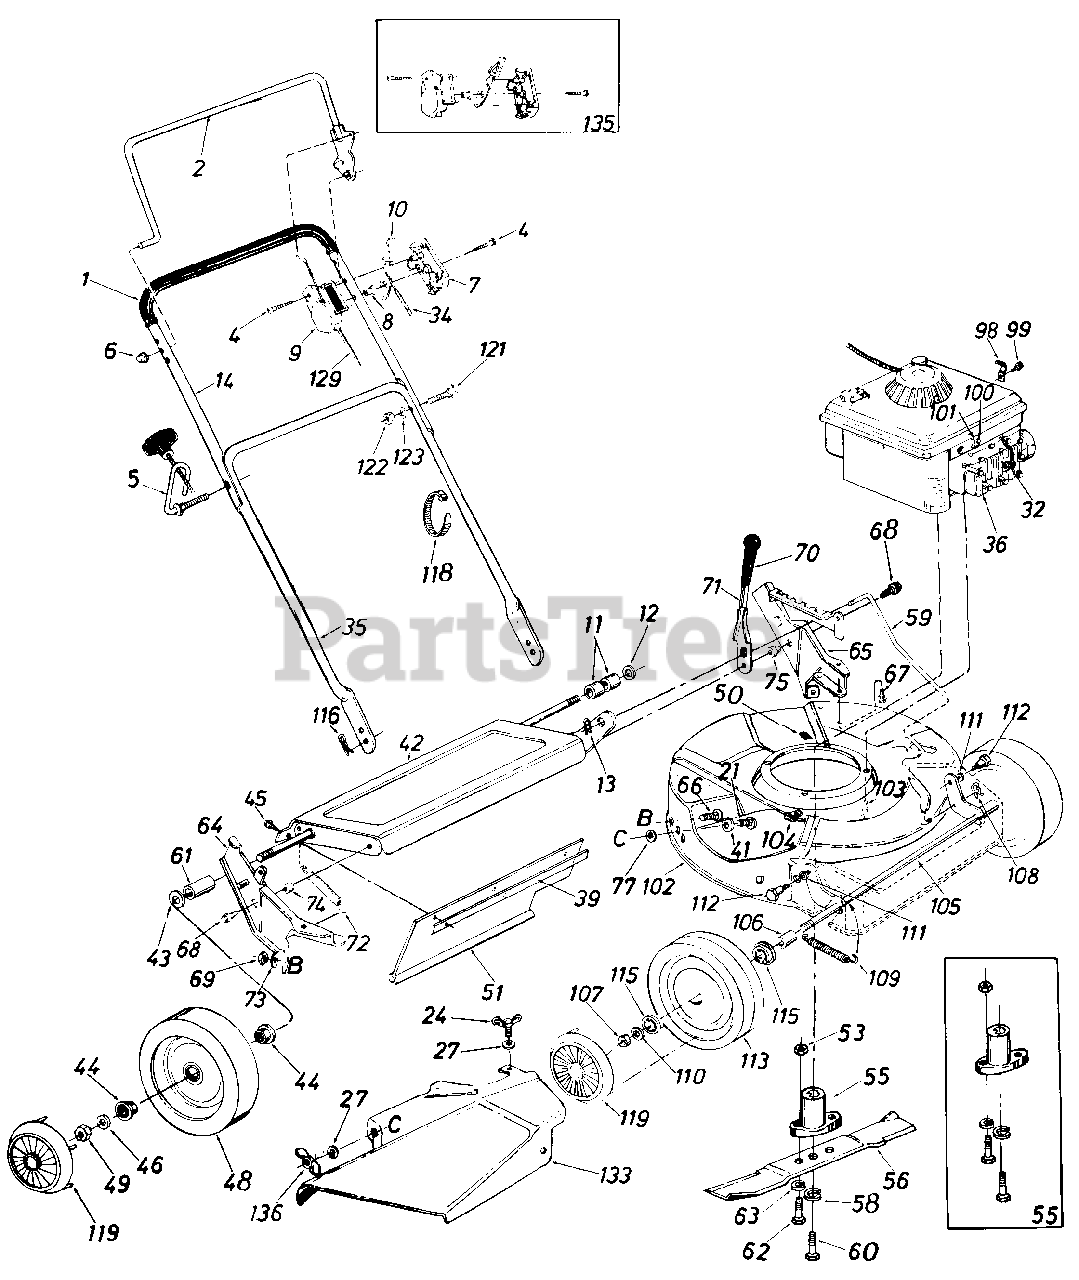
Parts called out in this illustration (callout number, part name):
1	Grip
2	Control Handle Ass'y. L.H.
4	Truss Mach. Scr. #12 x 1.50" Lg.
5	Rope Guide Bolt
6	Cap Speed Nut .31 Dia.
7	Control Panel Half
8	Control Disc Pin
9	Clutch Panel Half
10	Throttle Control Lever
11	Spacer .526" I.D. x .690" O.D. x .640" Lg
12	Fl-Wash. .531 " I.D. x .930" O.D.
13	Intern. Cotter Pin 5/16" Dia.
14	Upper Handle Chrome
21	Carriage Bolt 1/4-20 x .62" Lg.*
24	Wing Bolt 1/4-20 x .62" Lg.
27	Fl-Wash. .280" I.D. x .620" O.D.
32	Spark Plug Insulator
34	Throttle Control Wire 58.0"
35	Lower Handle Chrome
36	Engine
39	Retaining Strip
41	Fl-Wash. .344" I.D. x .62" O.D.
42	Rear Axle Ass'y
43	Fl-Wash. .531" I.D. x .930" O.D.
44	Flange Bearing 1/2" I.D.
45	Hex AB-Tap Scr. 1/4 x .62" Lg.
46	Fl-Wash. .531 " I.D. x .930" O.D.
48	Rear Wheel Ass'y. Comp.
49	Hex L-Nut 1/2-20 Thd.
51	Rear Flap 3.75" x 17.30" Lg.
53	Hex Nut 5/16-24 Thd.*
55	Blade Adapter Kit
58	L-Wash. 3/8" I.D. H.D.
59	Height Adj. Rod 1.50" x 19.42" Lg
60	Hex Bolt 3/8-24 x 2.25" Lg (Grade 5)
61	Spacer .51" I.D. x .69" O.D x .690" Lg
62	Hex Bolt 5/16-24 x 1.00" Lg (Grade 5)
63	L-Wash. 5/16" I.D.
64	R.H. Handle Wheel Brkt Ass'y
65	L.H. Handle Wheel Brkt Ass'y
66	Carriage Bolt 5/16-18 x .62" Lg.*
67	Hex Wash. Hd. B-Tap Scr. 5/16-18
68	Hex Wash. Hd. TT-Tap Scr. 3/8-16
69	Hex Nut 5/16-18 Thd.*
71	Height Adj. Lever 1.25 x 8.5" Lg
72	Extension Spring .50" O.D. x 3.80" Lg
73	Bell-Wash. .345" I.D. x .88" O.D.
74	Spacer .385" I.D. x .502" O.D. x .270" Lg.
75	Shld. Spacer .500" Dia. x .100
77	Bolt Retainer 1/4 x .50" O.D.
98	Throttle Control Cable Clip
99	Hex B-Tap Scr. #10 x .38" Lg.
100	Hex Sems Bolt #10-32 x .62" Lg.
101	Casing Clamp
102	21" Deck Ass'y
103	Hex Wash Hd. TT-Tap Scr. 3/8-16
104	Speed Nut 1/4-20 U-Type
105	Front Axle Ass'y.
106	Sleeve .526" I.D. x .690" O.D. x .880" Lg.
107	Hex L-Nut 1/2-20 Thd.
108	Intern. Cotter Pin 5/16" Dia.
109	Extension Spring .50" O.D x 3.20" Lg.
110	Fl-Wash. .531" I.D. x .930" O.D.
111	Intern. L-Wash. 3/8 x .56" O.D.
112	Shld. Bolt .623" Dia. x .425
113	Front-Wheel Ass'y. Comp.
115	Flange Bearing 1/2" I.D.
116	Intern. Cotter Pin 5/16" Dia.
119	Hub Cap Plastic
121	Curved Carr. Bolt 5/16-18 x 1.38" Lg.
122	Hex Nut 5/16-18 Thd.*
123	L-Wash. 5/16" I.D.*
129	Control Cable 43" Lg.
133	Side Chute Deflector
135	Kit Control Housing Comp.
